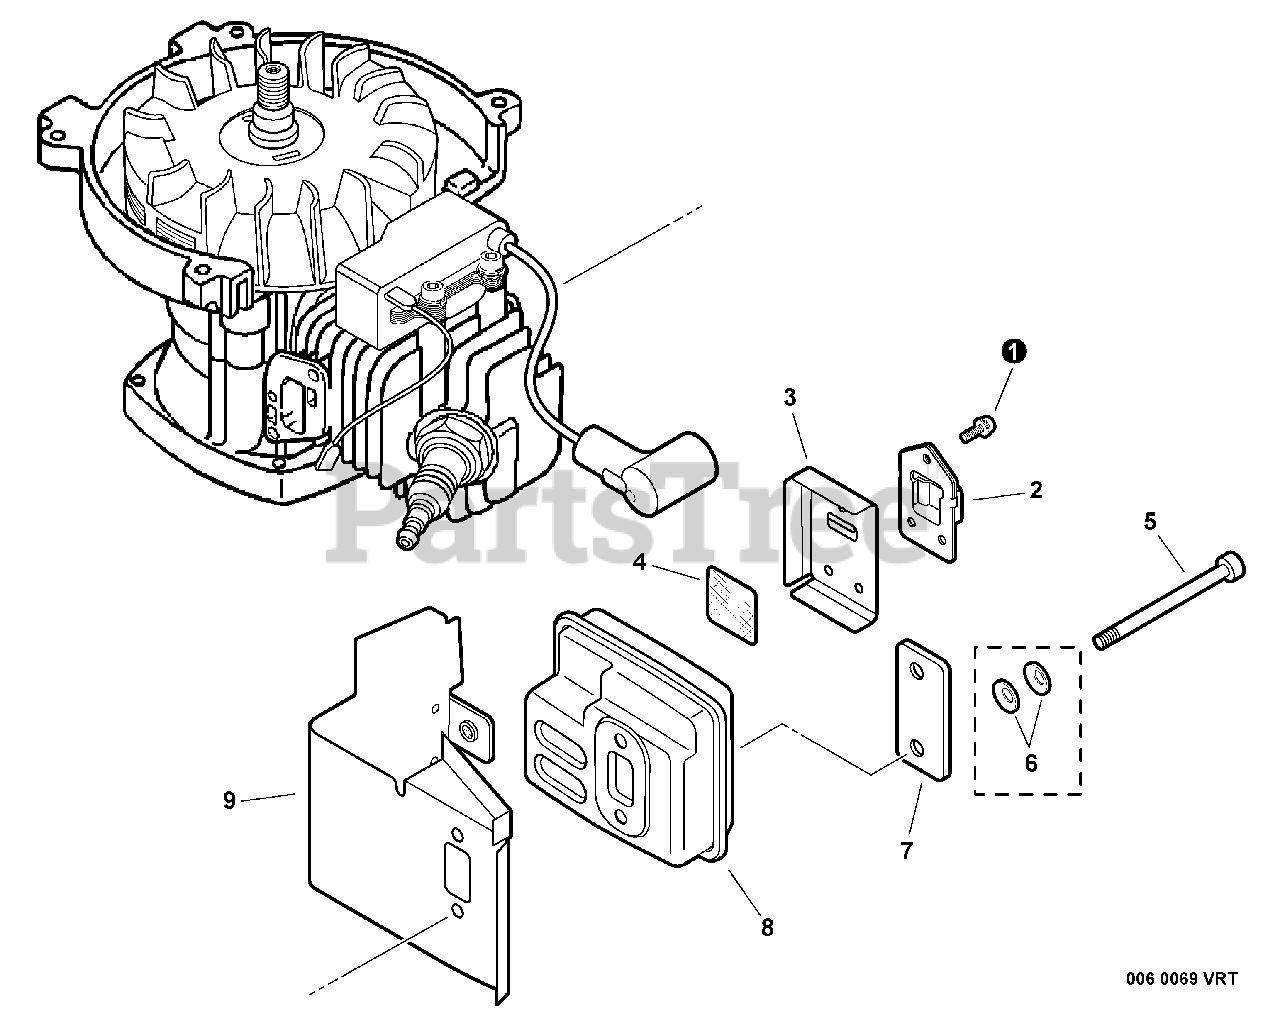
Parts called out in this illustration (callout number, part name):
1	SCREW - 4X10
2	GUIDE, EXHAUST
3	GASKET, EXHAUST
4	SCREEN, SPARK ARRESTOR
5	SCREW - 5X55
6	WASHER - CONICAL
8	MUFFLER
9	SHIELD, EXHAUST
